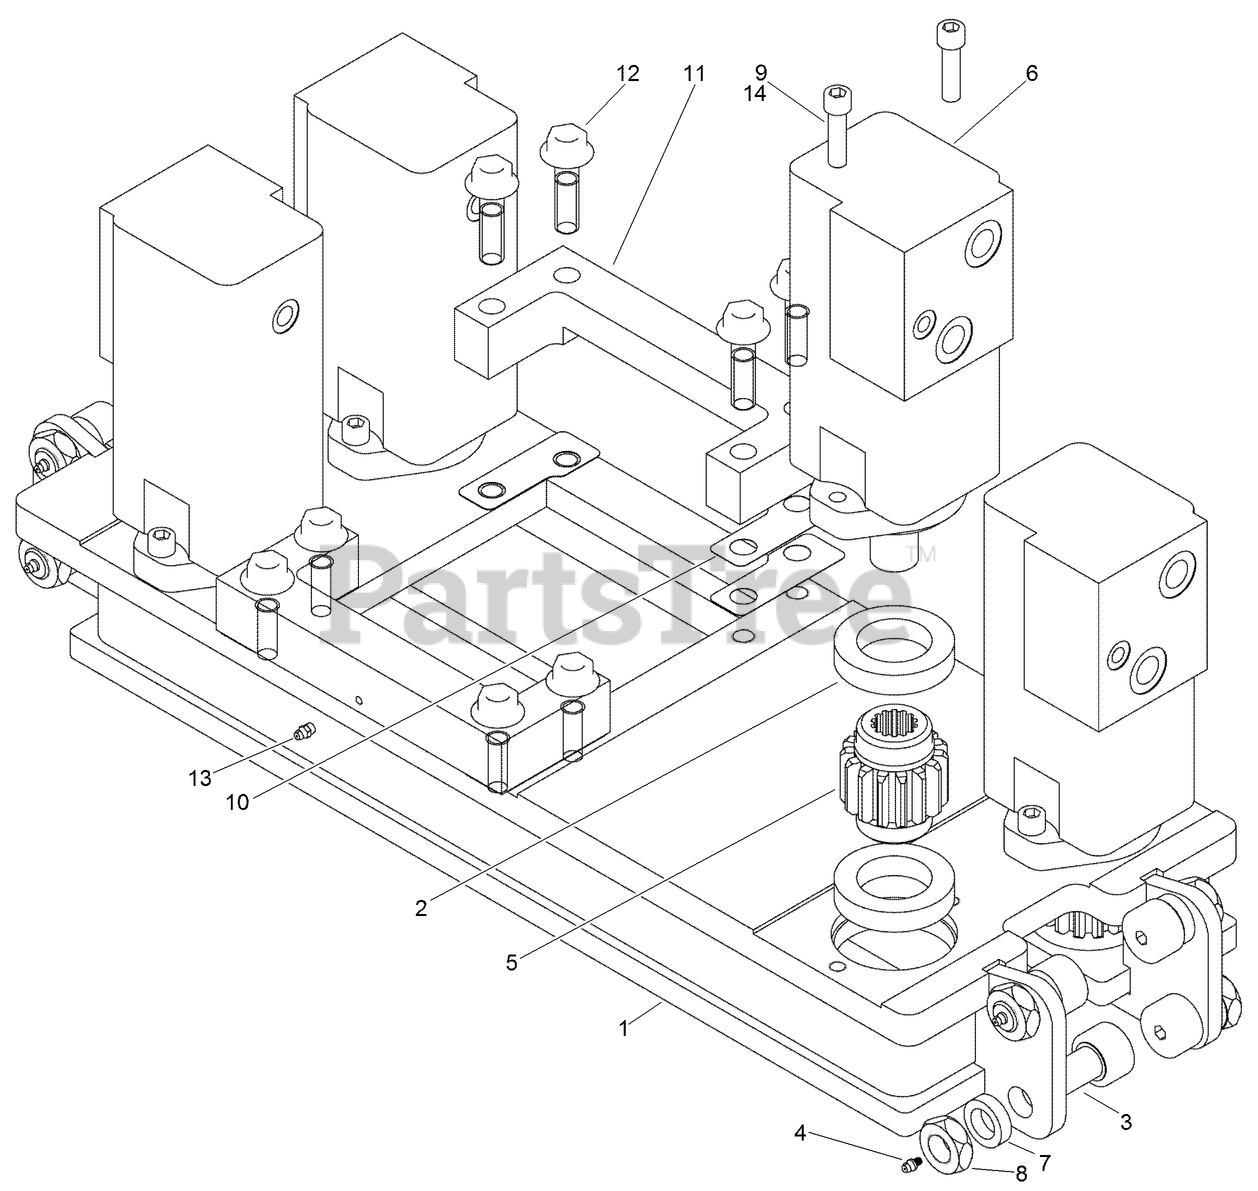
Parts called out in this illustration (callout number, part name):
1	CARRIAGE - Weldment/Machining
2	BEARING-BALL, DOUBLE SEALED
3	BEARING-ROLLER, CAM
4	FITTING - STR Grease 3/16
5	PINION-INPUT, 15T
6	HYD MOTOR ASM
7	SPACER-FOLLOWER, CAM
8	NUT - Jam, Hex, 7/8 - 14 NF, Nyloc
9	SCREW-HSFH
10	SHIM-BLOCK, ROTARY SLIDE
11	BLOCK - Rotary Slide
12	SCREW-FLANGE
13	FITTING-Lube 1/4-28 Tpr SAE-LT .54 Long
14	WASHER - Spring Lock Reg 12mm ZND
